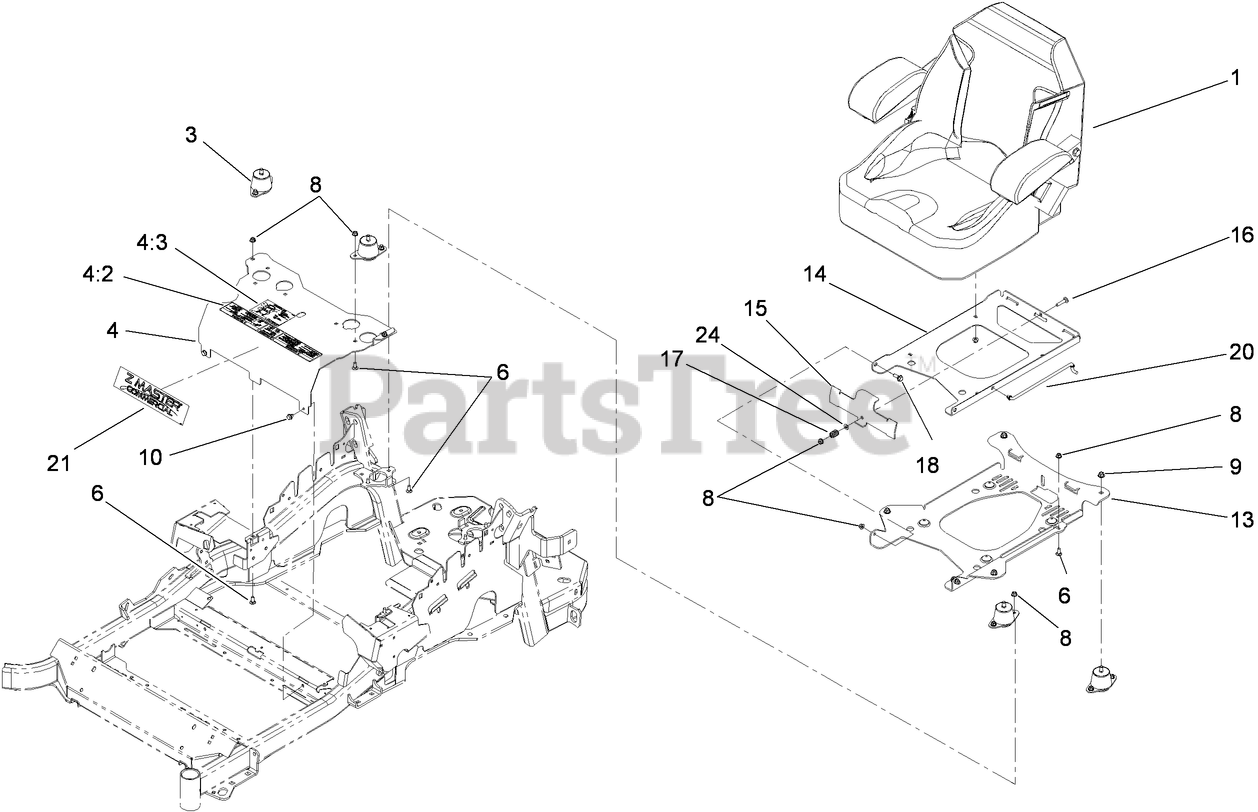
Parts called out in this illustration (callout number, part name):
1	SEAT-STANDARD
3	ISOLATOR-SEAT
4	MOUNT-SEAT
4:2	DECAL-CONSOLE
4:3	DECAL-SERVICE AID
6	SCREW-CARR
8	NUT-HF, NI
9	NUT-HF, NI
10	SCREW
13	PLATE-SUPPORT, SEAT TILT
14	PLATE-FRAME, SEAT TILT
15	PLATE-LATCH, SEAT
16	BOLT-CARR
17	SPRING-COMPRESSION
18	SCREW-SHOULDER
20	ROD-PROP
24	WASHER-PLAIN
